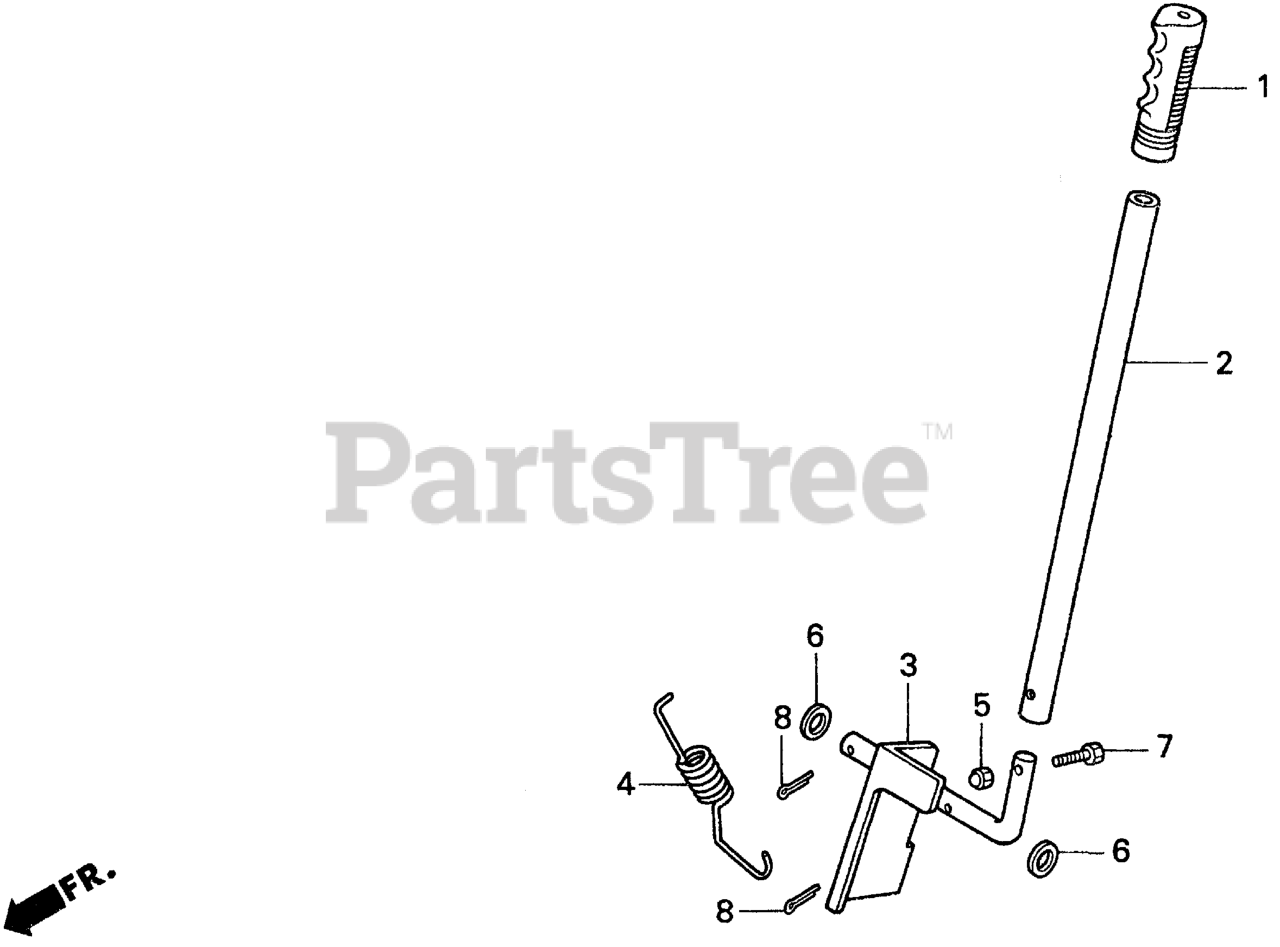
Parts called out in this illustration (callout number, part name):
1	GRIP, P.T.O. LEVER
2	LEVER A, P.T.O. SHAFT
3	LEVER B, P.T.O. CLUTCH
4	SPRING, P.T.O. LEVER
5	NUT, SELF-LOCK (5MM)
6	WASHER (13X20)
7	BOLT, HEX. (5X22)
8	PIN, COTTER (2.5MM)
